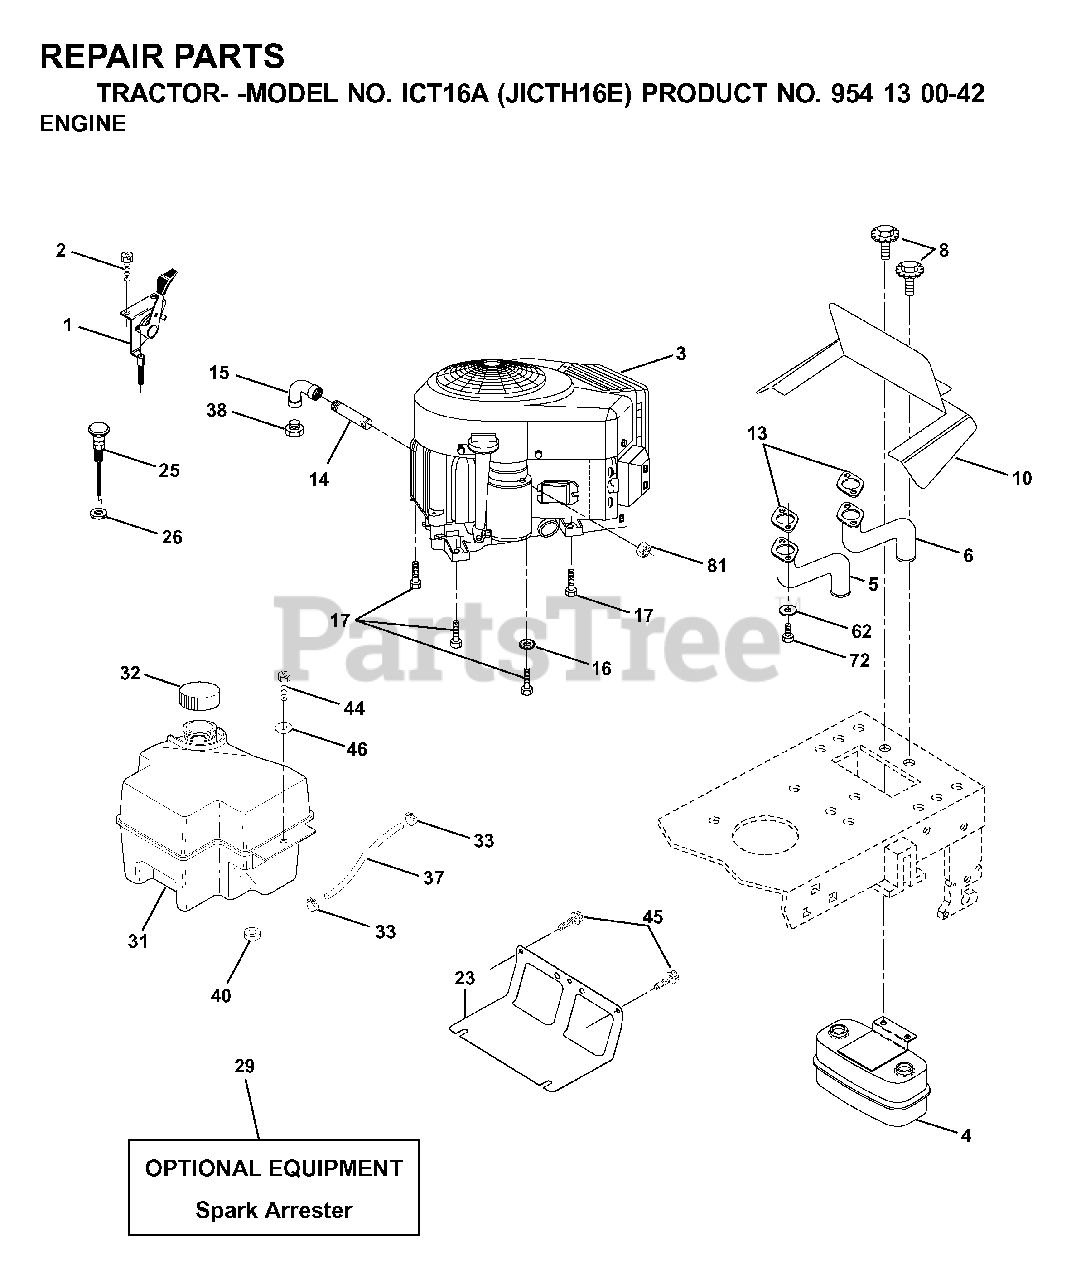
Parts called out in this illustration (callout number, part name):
1	CONTROL THROTTLE 36"
2	SCREW LT
4	MUFFLER.TWIN.CYL.LOW.TONE
5	TUBE MANIFOLD LH
6	EXHAUST TUBE RH
8	BOLT HEX WASHER HD 5/16-18
10	SHIELD.BROWNING.B&S
13	GASKET.MUFFLER
14	PIPE NIPPLE LT
15	ELBOW
16	LOCKWASHER
17	SCREW LT
23	SHEILD.BROWNING.DBR.GUARD
25	CONTROL, CHOKE
26	NUT KEPS 3/8 - 24 UNF
29	ARRESTER SPARK (OPTIONAL)
31	FUEL TANK
32	FUEL CAP
33	HOSE CLAMP
37	LINE.FUEL.20
40	GROMMET T
44	SCREW HEXWSHR 1/4-20X3/4
45	SCREW, 3/8-16X3/4
62	LOCKWASHER
72	SCREW
81	NUT
